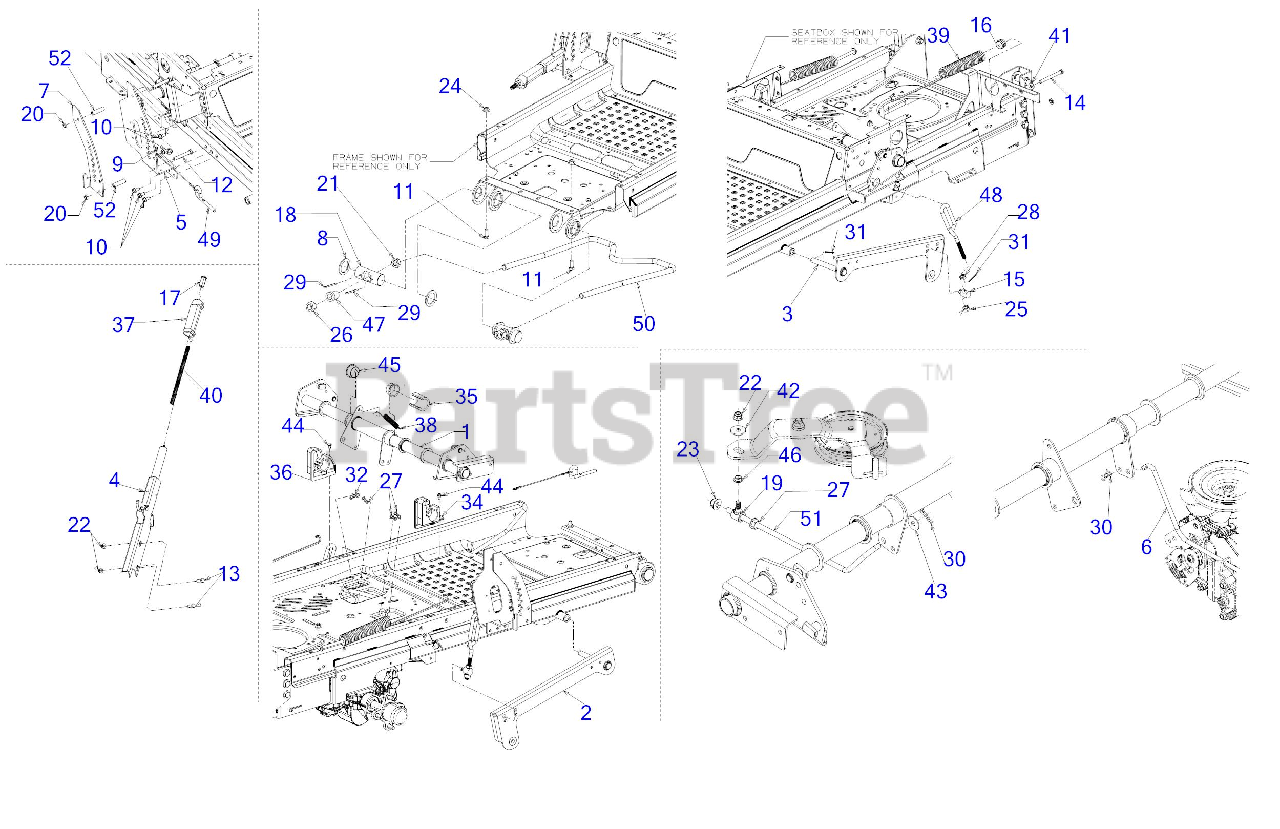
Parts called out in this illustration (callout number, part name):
4	LATCH HANDLE ASSEMBLY
6	BRAKE ROD ASSEMBLY
8	FLAT SPACER
9	HEX SCREW AB-TAP #10-16 x 0.500
10	SCREW 5/16-18 x .750
11	SCREW 3/8-16 x 1 GR5
12	HEX SCREW-3/8-16X2.5 GR5
13	SCREW 5/16-18 x .75 GR5
14	SCREW 3/8-16X4.25 GR5
15	LIFT LINK FERRULE
16	SPRING INSERT
17	LIFT HANDLE BUTTON
18	PIVOT LIFT PIN
19	FERRULE 3/8 X 0.375
20	JAM LOCK NUT
21	HEX JAM NUT 3/4-10
22	FLANGE LOCK NUT 5/16-18
24	FLANGE LOCK NUT
25	HEX NUT NYLOK 1/2-13
26	NYLOCK NUT 3/4-10
27	HEX FLANGE NUT
28	HEX NUT
29	COTTER PIN
30	BOW TIE COTTER PIN 1/4-5/16
31	COTTER PIN
32	BOW TIE COTTER PIN
34	DECK LIFT BRACKET
35	SPACER-1.375 SHAFT
36	DECK LIFT BRACKET (LH)
37	LIFT HANDLE GRIP
38	EXTENSION SPRING .63 x 4.95
39	EXTENSION SPRING 1.485 OD x 17.58
40	COMPRESSION SPRING
41	FLAT WASHER .385X.870X.090
42	FLAT WASHER 1.0 OD:.331 ID
43	FLAT WASHER 344X1.00
44	SHOULDER SCREW 1/4-20X.50 19"PSH
45	FLANGE BEARING
46	FLANGE BEARING
47	FLANGE BEARING
48	LIFT ADJUSTMENT LINK
50	DECK HANGER ROD
51	BRAKE DISENGAGEMENT ROD
